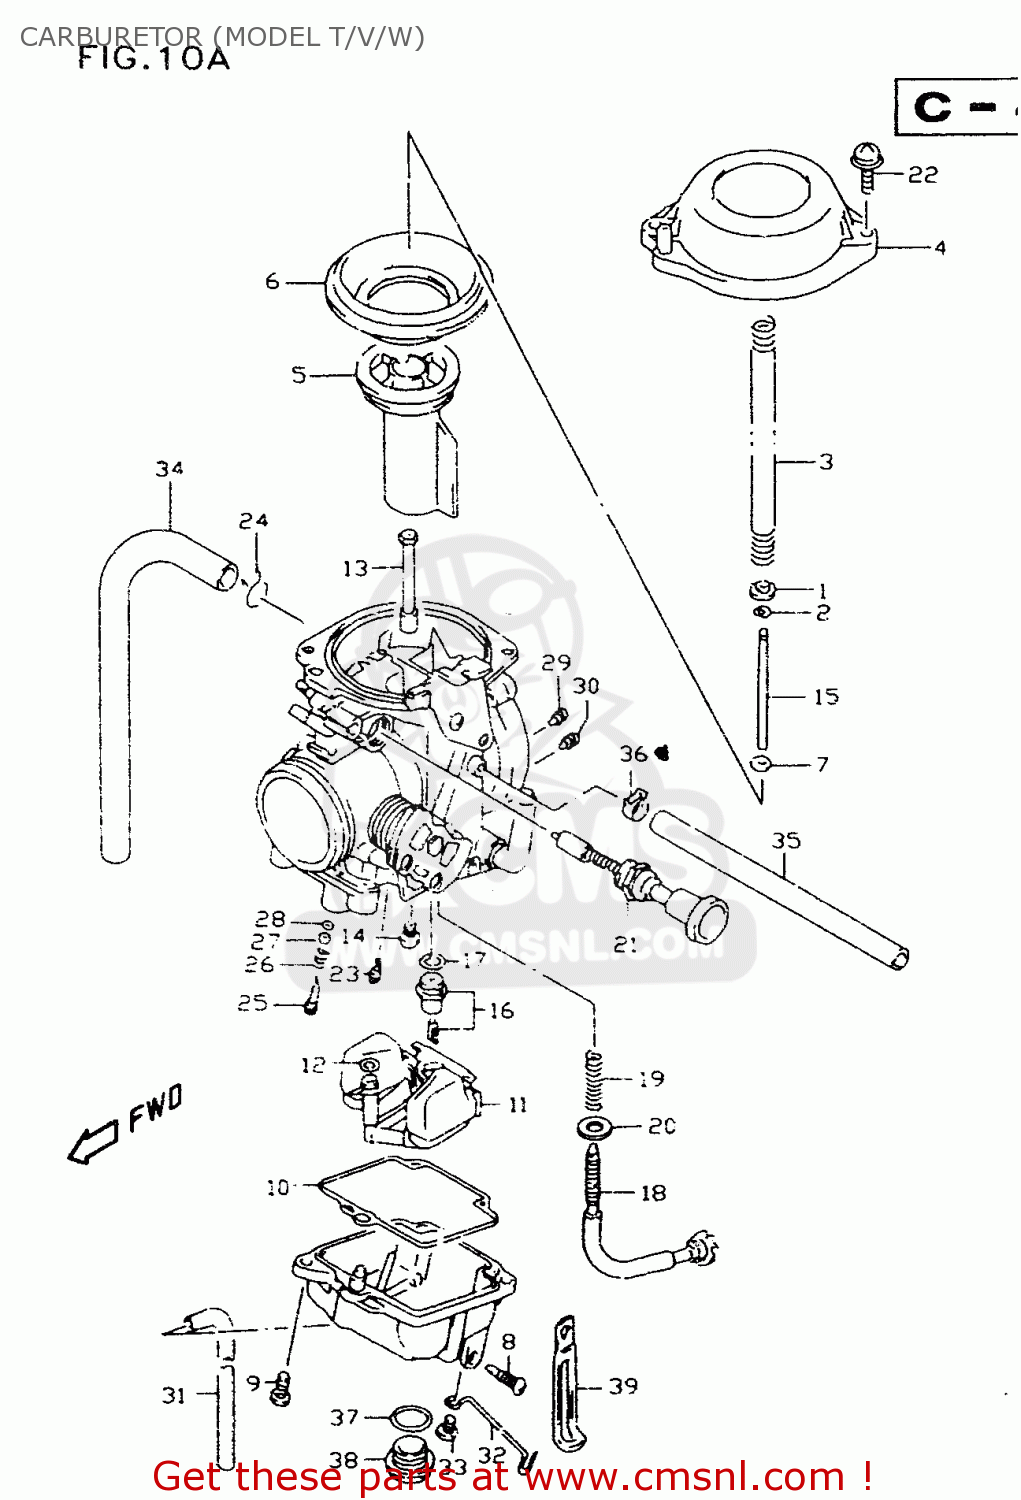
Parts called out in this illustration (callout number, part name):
1	RING
2	E RING
3	SPRING
4	COVER,DIAPHRAGM
5	VALVE PISTON
6	DIAPHRAGM
7	RING
8	SCREW,DRAIN
9	SCREW
10	GASKET,FLOAT CHAMBER (NAS)
11	FLOAT ASSY
12	O RING
13	JET,NEEDLE(O-5)
14	JET,MAIN(135)
15	NEEDLE,JET
16	VALVE ASSY,NEEDLE
17	O-RING,NEEDLE VALVE
18	ADJUSTER
19	SPRING,THROTTLE SCREW
20	WASHER,STARTER SHAFT
21	PLUNGER ASSY
22	SCREW
23	JET,PILOT(37.5)
24	CLIP
25	SCREW,PILOT
26	SPRING
27	WASHER
28	O RING,PILOT AIR SCREW
29	JET,AIR(1.2)
30	JET,AIR(0.6)
31	HOSE(3X5X600)
32	CLIP
33	SCREW
34	HOSE(7X12X600)
35	HOSE(5X8.2X600)
36	CLIP
37	SCREW,GUIDE
38	O RING,DRAIN PLUG
39	CLAMP(L:45)
